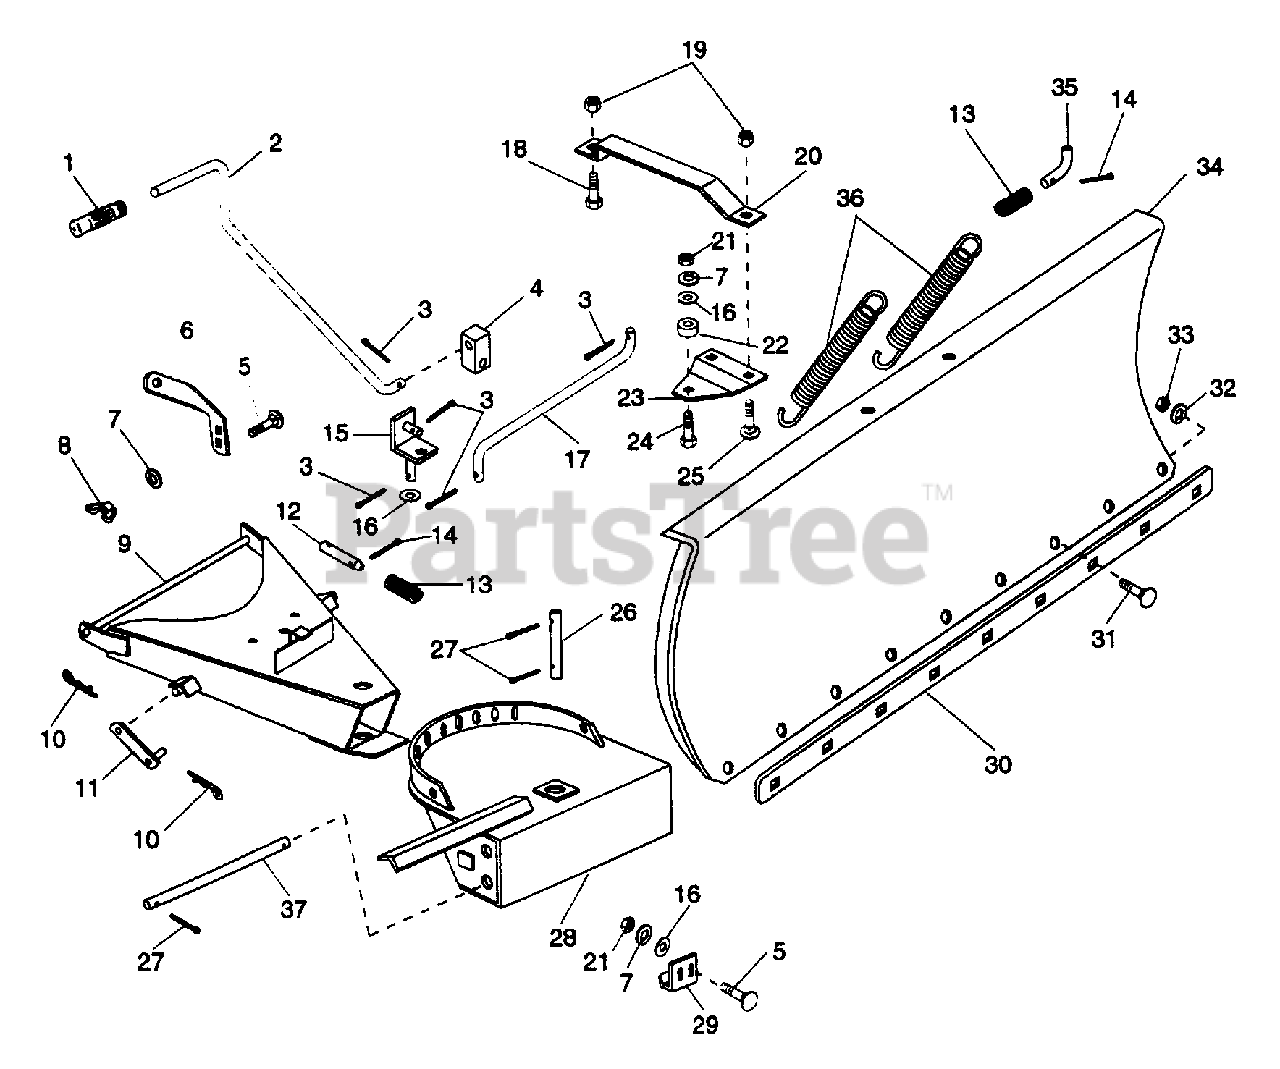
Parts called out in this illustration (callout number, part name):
1	GRIP - 3/8 ID X 2 7/8 - BLACK
3	PIN-COTR .12X.75 PL
4	UNIVERSAL BLOCK JOINT
5	BLT-RDHDSQNK .38-16X1.0 PL
6	SUPPORT
7	WSHR-LK .375X.094 MED PL
8	NUT-WING .375-16 ZCC
9	54 IN FRAME
10	PIN-HAIR INT .14X.4X2.75
11	ARM, LIFT LINK
12	LATCH PIN
13	SG-COMP .080X.85X1.44
14	PIN-COTR .12X1.0 PL
16	WSHR-FL-STL .438X1.0X.083 PL
18	BLT-HEX .31-18X1.25 PL GR2
19	NUT-LK .312-18 GR A PL
21	NUT-HEX .375-16
22	SPACER .406X.749X.162
23	PIVOT PLATE
24	BLT-HEX .38-16X1.00 PL
25	BLT-RDHDSQNK .31-18X.75 SHT PL
27	PIN-COTR .18X1.0 PL
28	SUPPORT
29	SKID SHOE
30	WEAR PLATE
31	BLT-RDHDSQNK .31-18X1.00 PL
32	WSHR-LK .312X.097 PL HVY
33	NUT-HEX .312-18
34	54 IN BLADE
35	JACK PIN
36	SG-TENS .187X1.50X9.94 WLD 40
